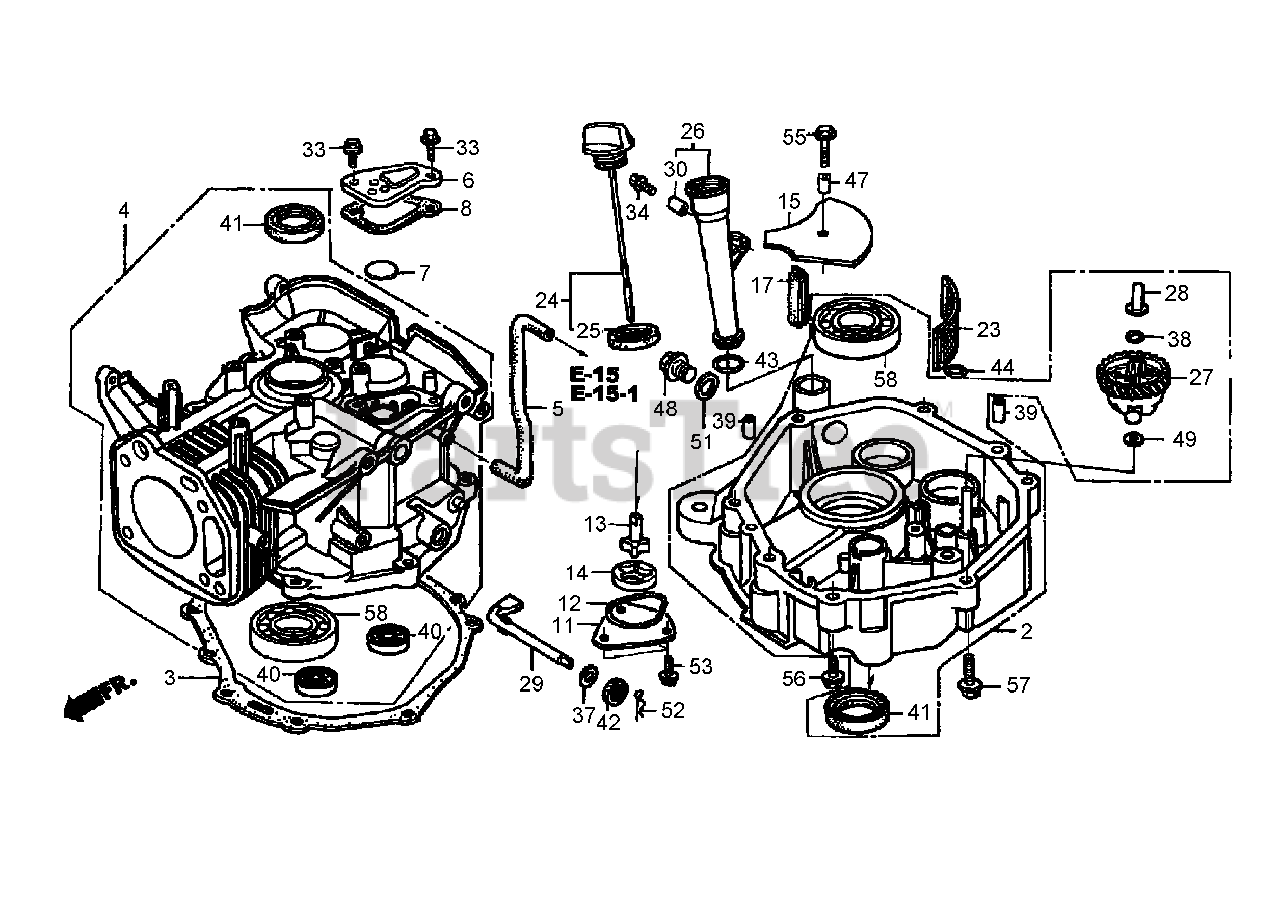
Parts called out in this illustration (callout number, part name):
2	OIL PAN ASM
3	GASKET-PAN , OIL
4	CYLINDER ASM
5	TUBE-BREATHER
6	CAP-CHAMBER, BREATHER
7	VALVE- BREATHER
8	GASKET-CAP, BREATHER
11	COVER-PUMP, OIL
12	O-RING (PUMP COVER)
13	ROTOR (INNER)
14	ROTOR-PUMP, OIL (OUTER)
15	PLATE-FILTER, OIL
17	RUBBER-RETURN, OIL
23	SCREEN-FILTER, OIL
24	OIL FILLER CAP ASM
25	GASKET-CAP, OIL FILLER
26	EXTENSION-FILLER, OIL
27	GOVERNOR ASM
28	SLIDER-GOVERNOR
29	SHAFT-ARM, GOVERNOR
30	Collar-Extension
33	BOLT-FLANGE (6X12) (C T200)
34	BOLT- FLANGE (6X35)
37	WASHER-THRUST (8.1MM)
38	CLIP-HOLDER, GOVERNOR
39	PIN-DOWEL
40	BEARING-BALL, RADIAL (6202)
41	SEAL-OIL (35X52X8)
42	SEAL-OIL
43	O-Ring (22.5X2.2)
44	O-RING (11.8X2.4)
47	COLLAR-SETTING, OIL FILTER
48	BOLT-PLUG, DRAIN (20MM)
49	WASHER-PLAIN (6MM)
51	WASHER-PLUG, DRAIN (20MM)
52	PIN-LOCK
53	BOLT-FLANGE (6X12)
55	BOLT-FLANGE (6X25)
56	BOLT-FLANGE (8X40)
57	BOLT-FLANGE (8X60)
58	BEARING-BALL, RADIAL
58	BEARING-BALL, RADIAL (6207)
